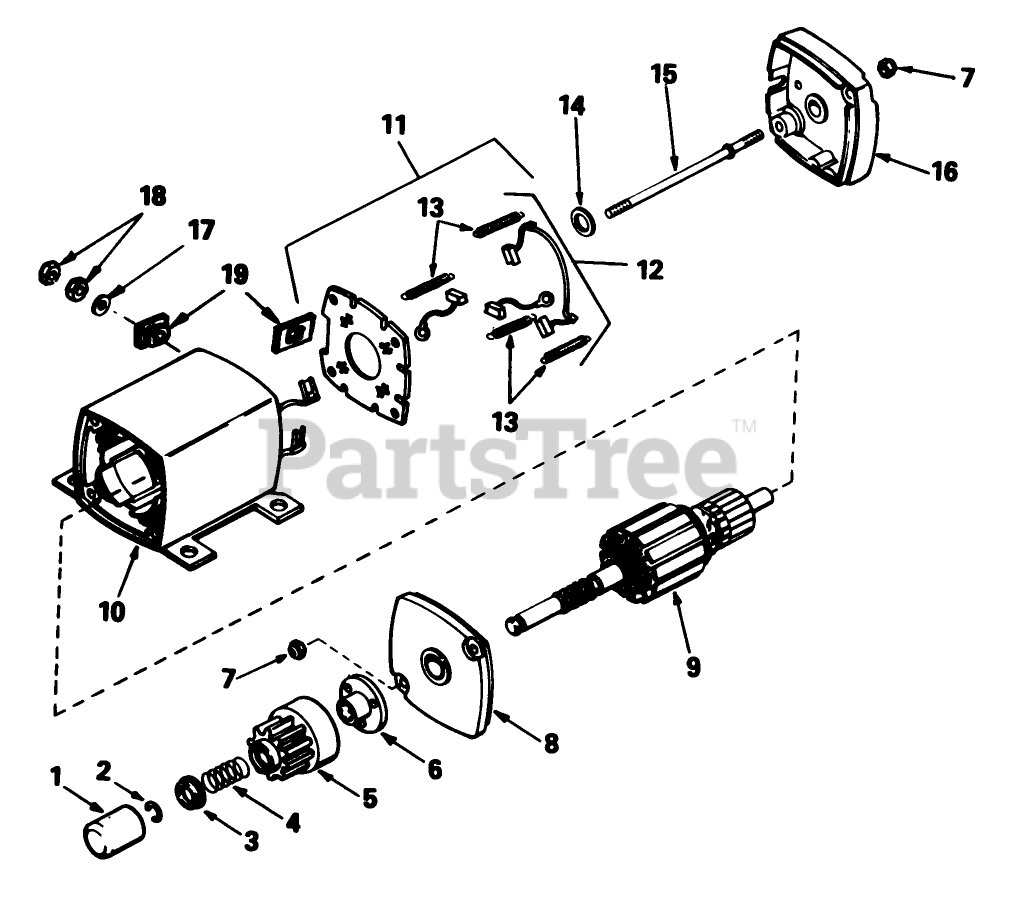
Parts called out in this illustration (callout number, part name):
1	Cover-Dust
2	Ring-Retainer
3	Retainer-Spring
4	Spring-Anti Drift
5	Gear
6	Nut-Engaging
7	Nut-Lock
8	Cap Assy., Drive End
9	Armature
10	59 Housing Assy.
11	Card Assy., Brush (Incl. No. 12)
12	Brush Spring Kit (Incl. 4 pcs. of #13)
13	1545D SUP TO W/3256
14	Washer-Thrust
15	Bolt
16	2035A67 WIZARD W/34
17	Washer
18	Nut-Hex
19	Terminal Insulators
